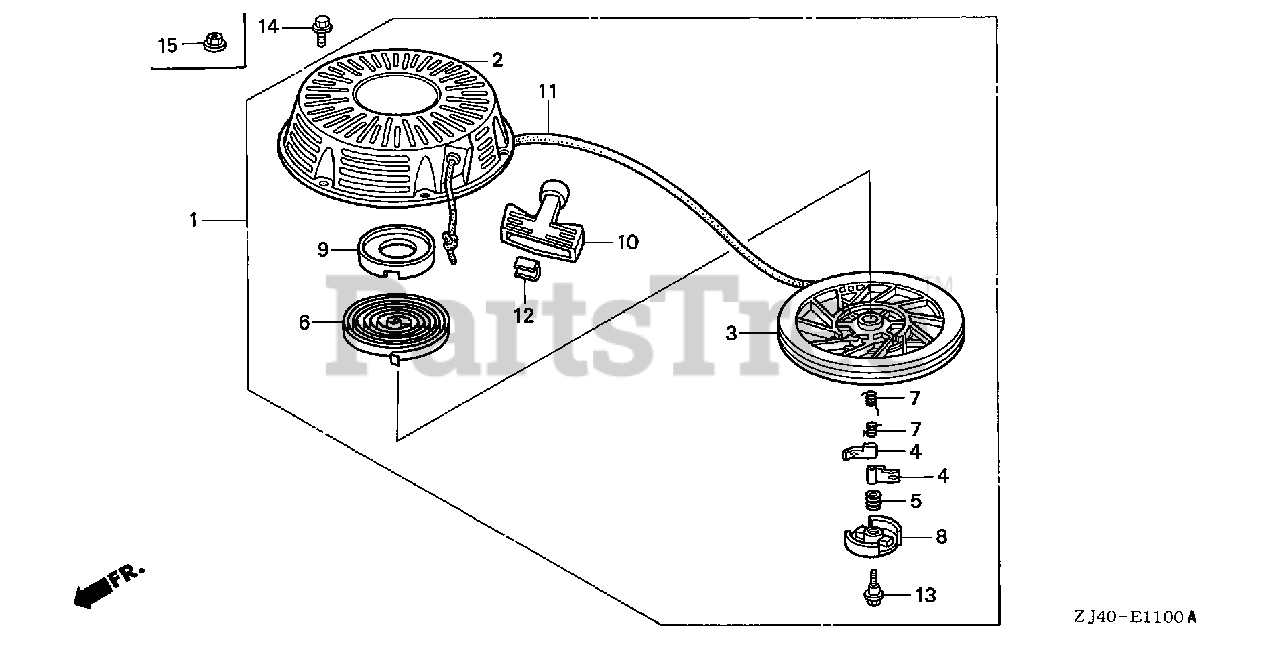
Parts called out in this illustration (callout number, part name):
1	STARTER ASSY., RECOIL *R8* (BRIGHT RED)
1	STARTER ASSY., RECOIL *R280* (POWER RED)
2	CASE, RECOIL STARTER *R8* (BRIGHT RED)
3	PULLEY, RECOIL STARTER
4	RATCHET, STARTER
5	SPRING, FRICTION
6	SPRING, STARTER RETURN
7	SPRING, RATCHET
8	RETAINER, SPRING
10	GRIP, STARTER
11	ROPE, RECOIL STARTER
12	GRIP, REINFORCEMENT
13	SCREW, CENTER
14	BOLT, FLANGE (6X10)
